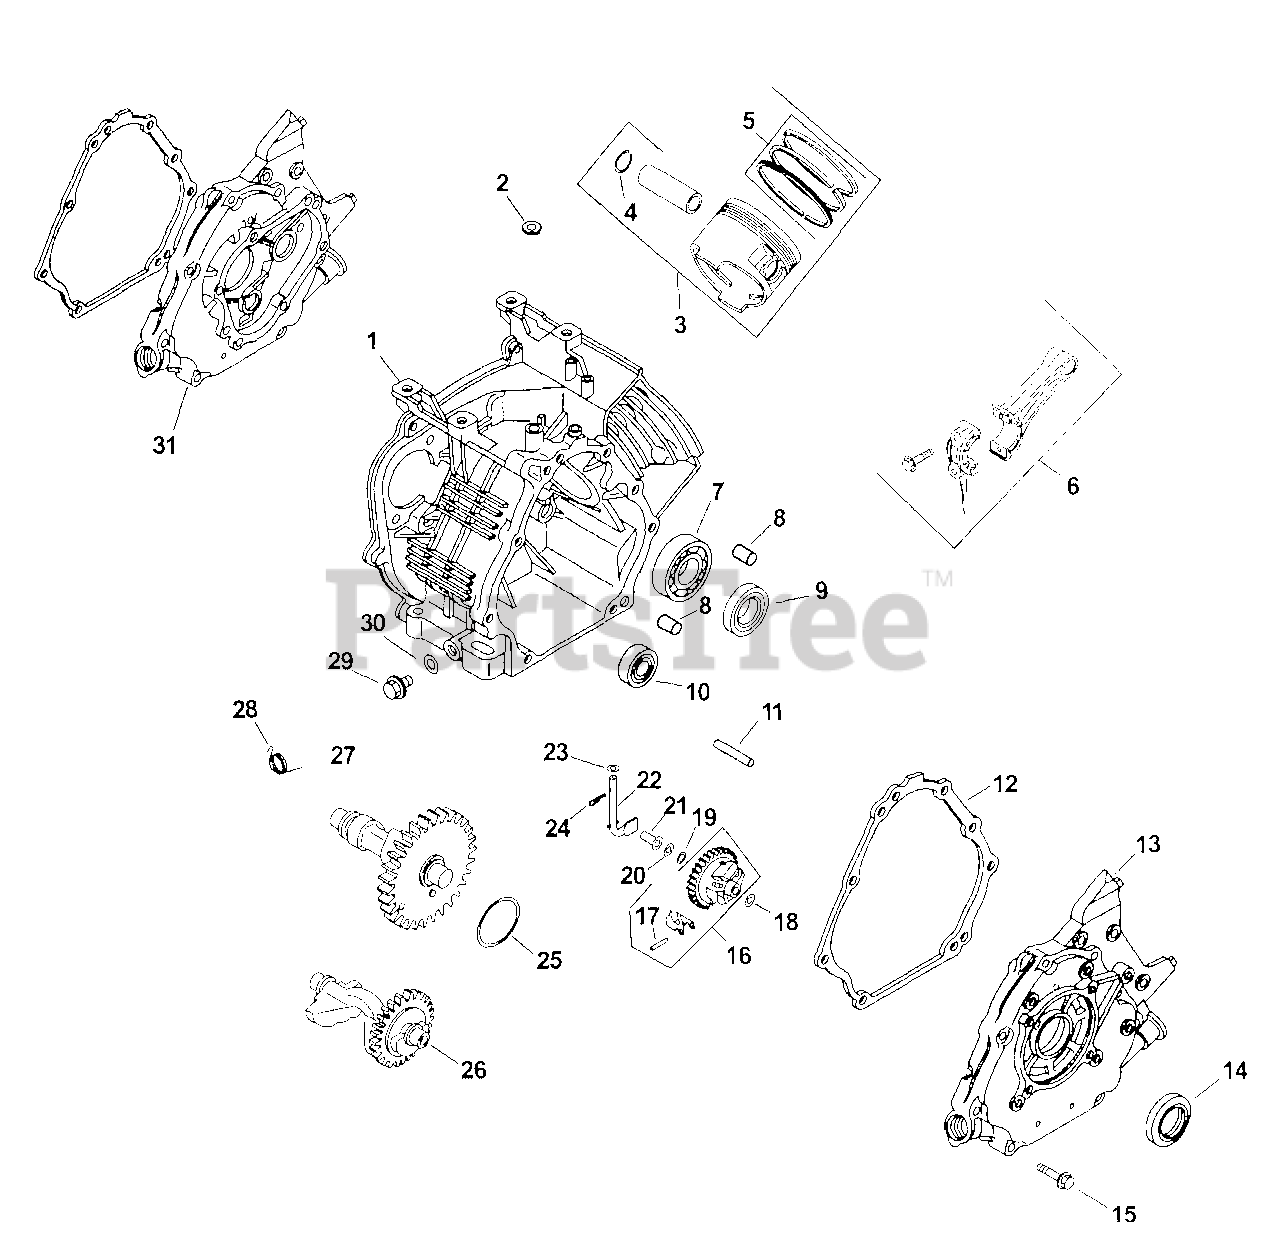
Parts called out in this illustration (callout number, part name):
1	CRANKCASE W/1 DRAIN - DISC.
2	OIL SEAL-GOVERNOR SHAFT
3	PISTON W/RING SET STD
3	PISTON W/RING SET (+.25MM)
3	PISTON W/RING SET (+.50MM)
4	RING, RETAINER
5	RING SET, STD
5	RING SET, (.25MM)
5	RING SET, (.50MM)
8	DOWEL PIN
11	SHAFT, FLYWEIGHT
12	GASKET, CLOSURE PLATE
13	CLOSURE PLATE
16	GOVERNOR GEAR ASSEMBLY
17	PIN - USE APPL GOV GEAR ASSY
19	SNAP RING
22	SHAFT, GOVERNOR CROSS
26	BALANCE SHAFT
28	SPRING, ACR
29	PLUG, DRAIN
30	GASKET, PLUG
6303205-S	OIL SEAL, G.R.
6321101-S	BOLT, CONN. ROD
6375503-S	KIT, CARBURETOR REPAIR (CS8.5,10)
